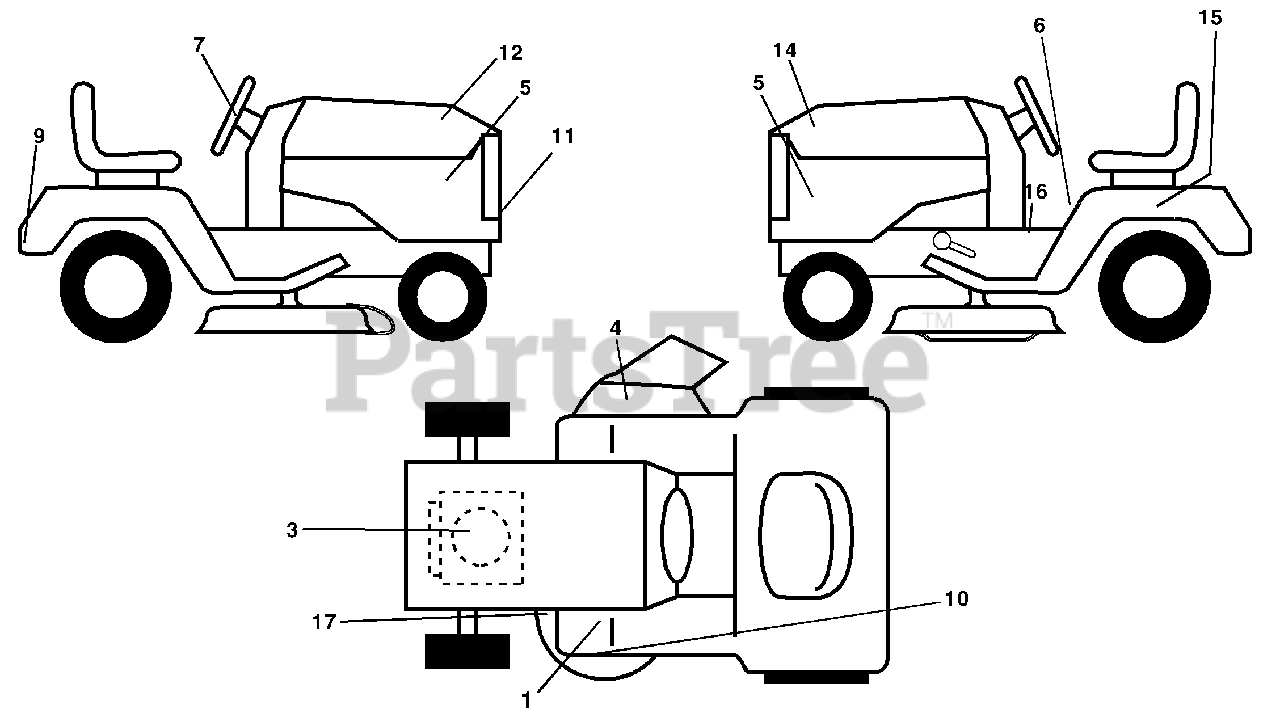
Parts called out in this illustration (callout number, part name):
1	Decal, Clutch/Brake Eng/Fr
3	Decal, Engine HP
4	Decal Warning
5	Decal, Pnl Sd
6	Decal, Fender Danger English
7	Decal Ins Str Wh
9	Decal Fender
10	Decal, Deck Grasseater
11	Decal, Grille Weedeater
12	Decal, Hood RH
14	Decal, Hood LH
15	Decal, Caution, Battery
16	Decal, Oper Sdl P/L Gear Dr Eng
17	Decal, V-Belt Sch.
